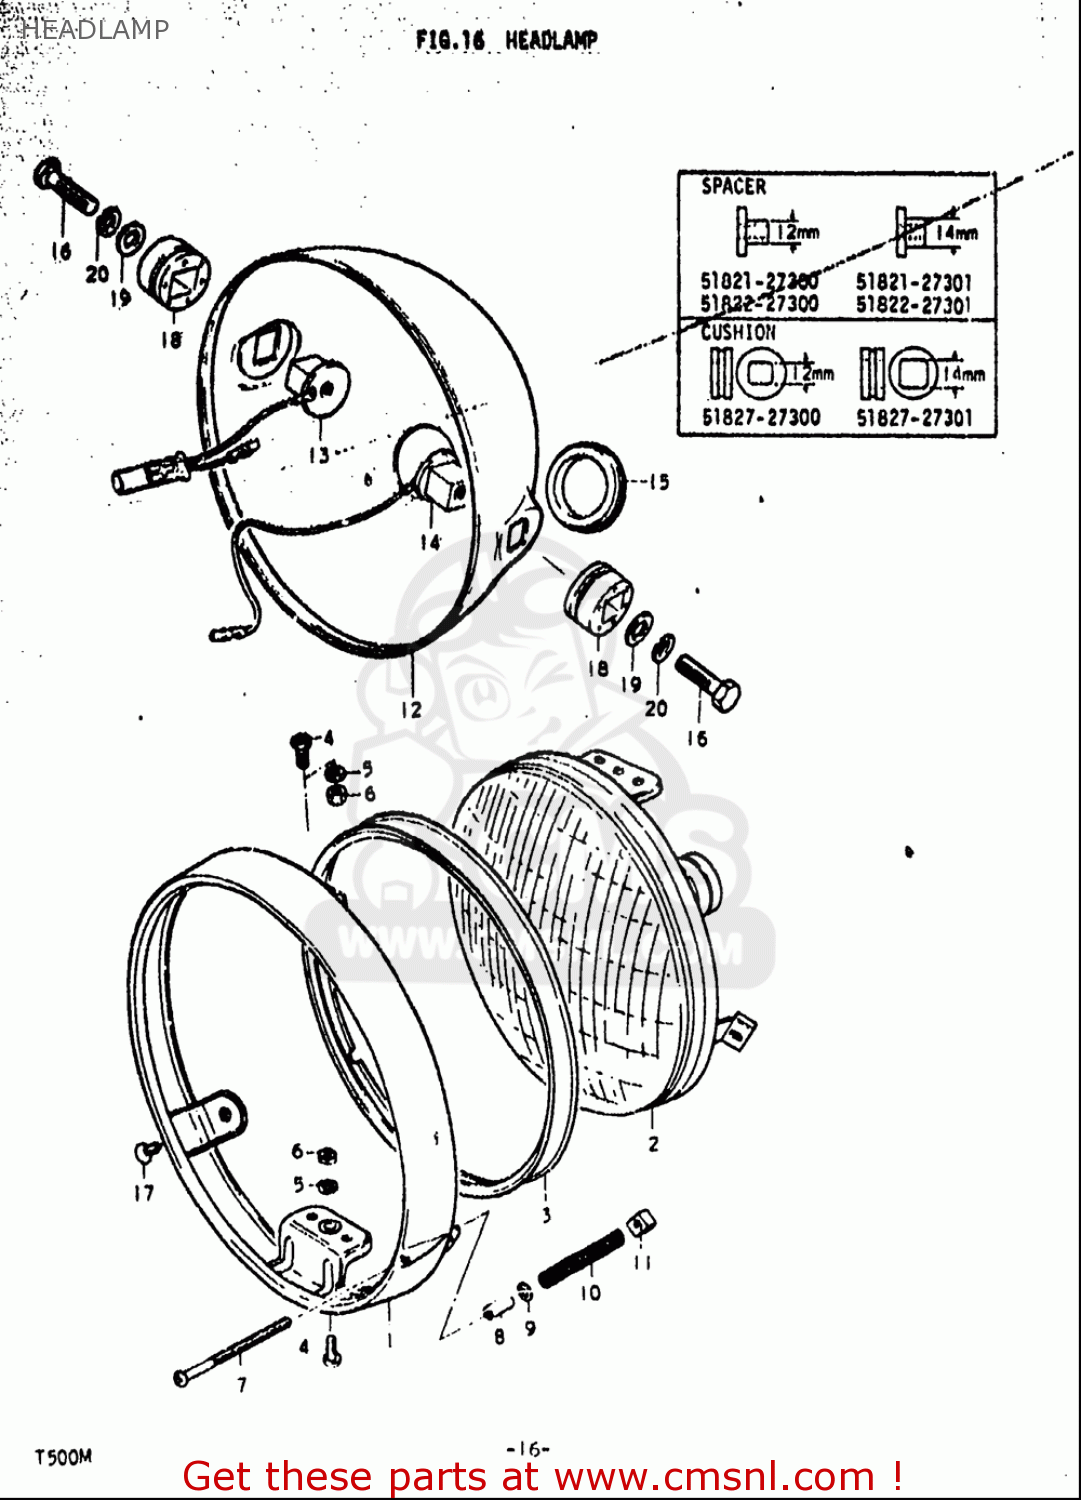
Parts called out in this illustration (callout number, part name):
3	RETAINER,HEADLAMP
4	H/LAMP LENS UNIT FITING SCRE
5	WASHER,LOCK
6	NUT
7	SCREW
9	WASHER
11	NUT
16	BOLT
17	SCREW
18	CUSHION,HEADLAMP HOUSING
19	WASHER
20	WASHER,LOCK
